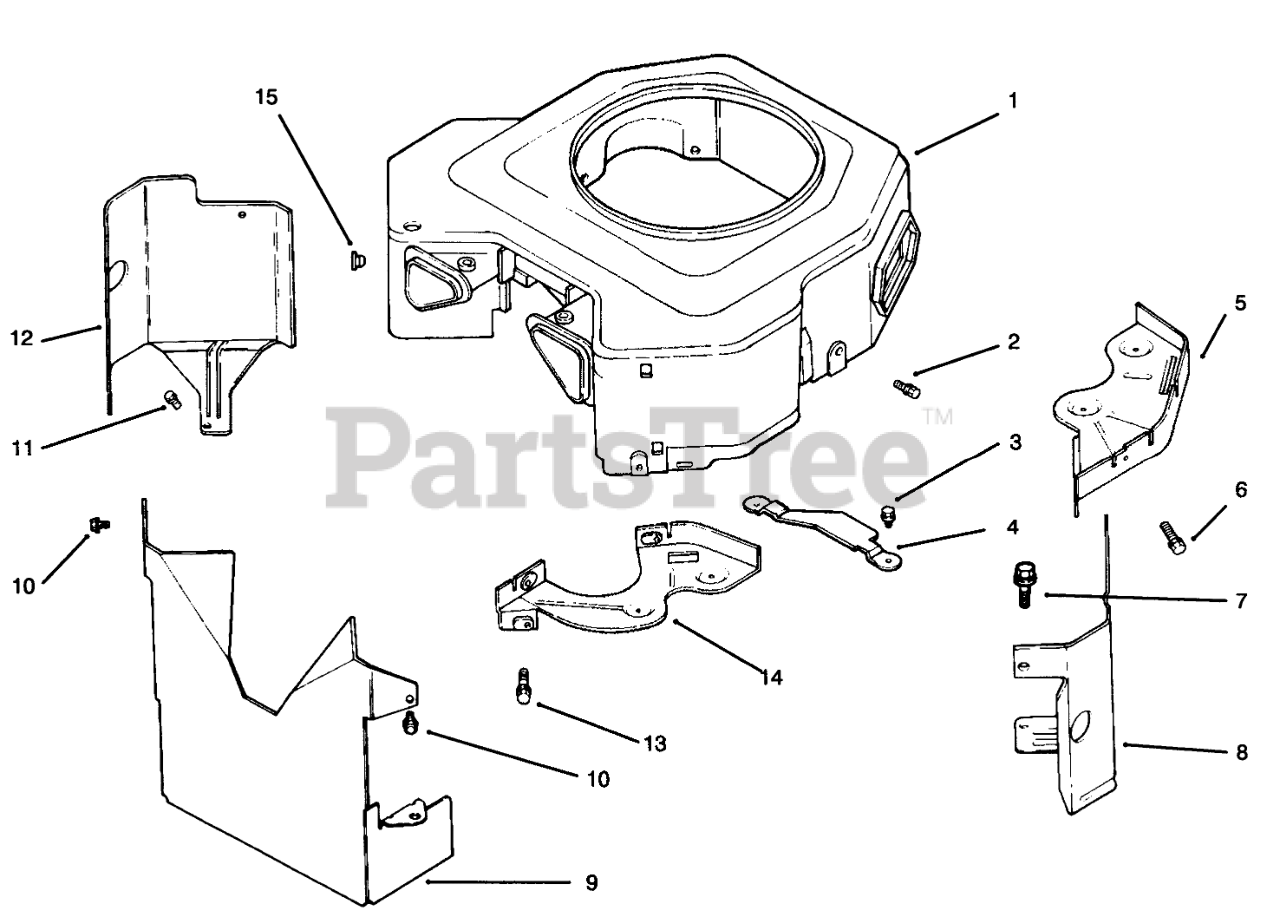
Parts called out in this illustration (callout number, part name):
1	Housing-Blower
3	Screw
4	Guard-Flywheel
5	Plate-Backing #2 Side
6	Screw
7	Screw
8	Baffle-Cylinder, #2
9	Baffle-Valley
10	Screw
12	Baffle-Cylinder #1 Side
13	Screw
14	Plate-Backing #1
15	Nut-Plastic
